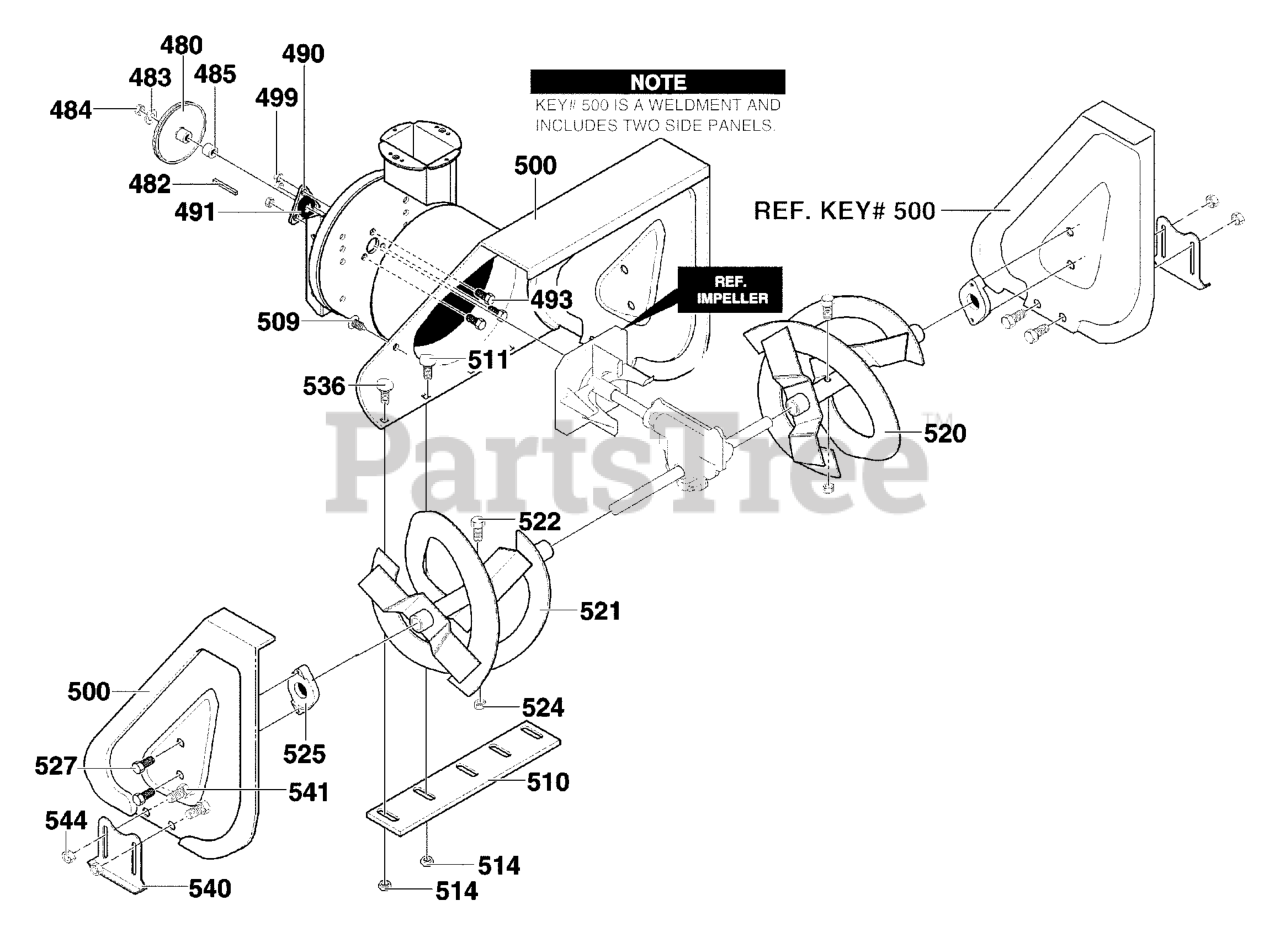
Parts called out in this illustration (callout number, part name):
480	PULLEY, 4L 8.40
482	KEY, SQUARE
483	WASHER, FLAT
484	NUT, 1/2-20 REGHXCTRLK
485	SPACER, SLEEVE
490	RETAINER, BALL BRNG
491	BEARING, BALL
493	SCREW, 5/16-18 x 0.75
499	NUT, 5/16-18 HEXWDFLLK
500	HOUSING, ASSY
510	BLADE, SCRAPER
511	BOLT, 5/16-18 X .75
514	NUT, 5/16-18
520	AUGER, ASSY, LH
521	AUGER, ASSY, RH
522	BOLT, .467X.235 HHSH 5/16-18
524	NUT, 5/16-18 REGHEXCTRLK
525	AUGER SHAFT BEARING
527	SCREW, 5/16-18 x 0.75
536	BOLT, 5/16-18X.75
540	SKID, HEIGHT ADJUST
541	CARR. BOLT, 5/16-18X.75
544	NUT, 5/16-18 REGHEX
